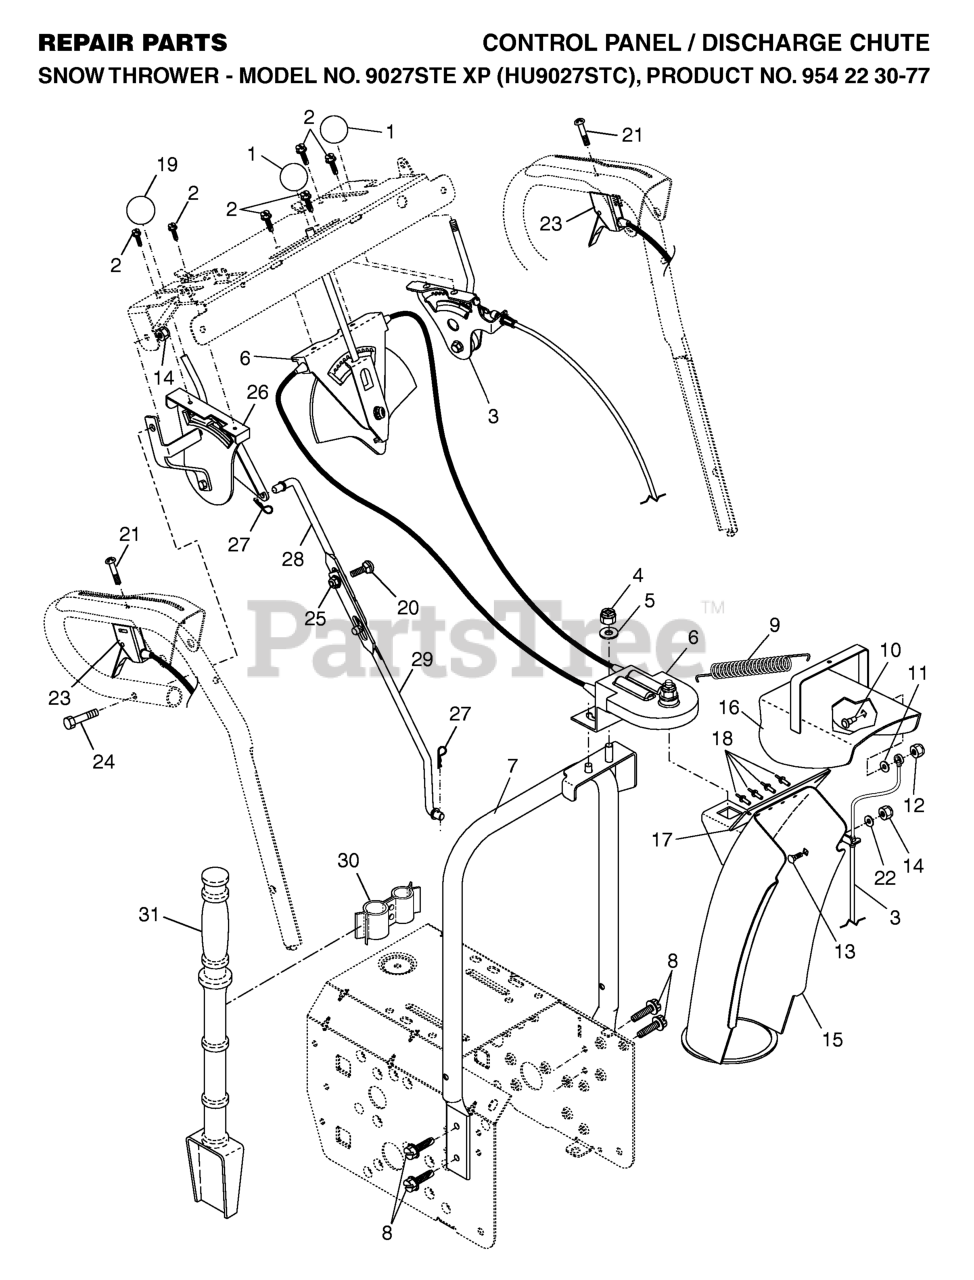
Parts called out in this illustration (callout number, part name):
1	KNOB, LEVER
2	SCREW #10-24 X 5/8
3	CONTROL ASSY, DEFLECTOR
4	NUT
5	WASHER
6	CONTROL ASSY, CHUTE ROTATER
7	SUPPORT CHUTE ROTATER
8	SELF-TAPPING SCREW 5/16-18X3/4
9	SPRING.DEFLECTOR.REM.CHUTE
10	BOLT, SHOULDER
11	WASHER, NYLON FRICTION
12	LOCKNUT.NYLOC.1/4-20
13	BOLT
14	NUT.71038.31-18.HEX.NYLOCK
15	CHUTE ASSY
16	DEFLECTOR.WELDMENT.PNT.ORANGE
17	SEAL, DEFLECTOR
18	RIVET BLIND
19	RP KNOB, SPEED CONTROL LEVER
20	BOLT
22	WASHER.20X8.5
23	STEERING.CONTROL.SNOW.BLUE
25	NUT.FLANGE.5/16
26	LEVER ASSEMBLY, SPEED CONTROL
27	SPRING RETAINER
28	ROD, UPPER SPEED CONTROL
29	ROD, LOWER SPEED CONTROL.SNOW
30	CLAMP.ASM.CLEANOUT.TOOL.SNOW
31	CLEAN OUT TOOL
